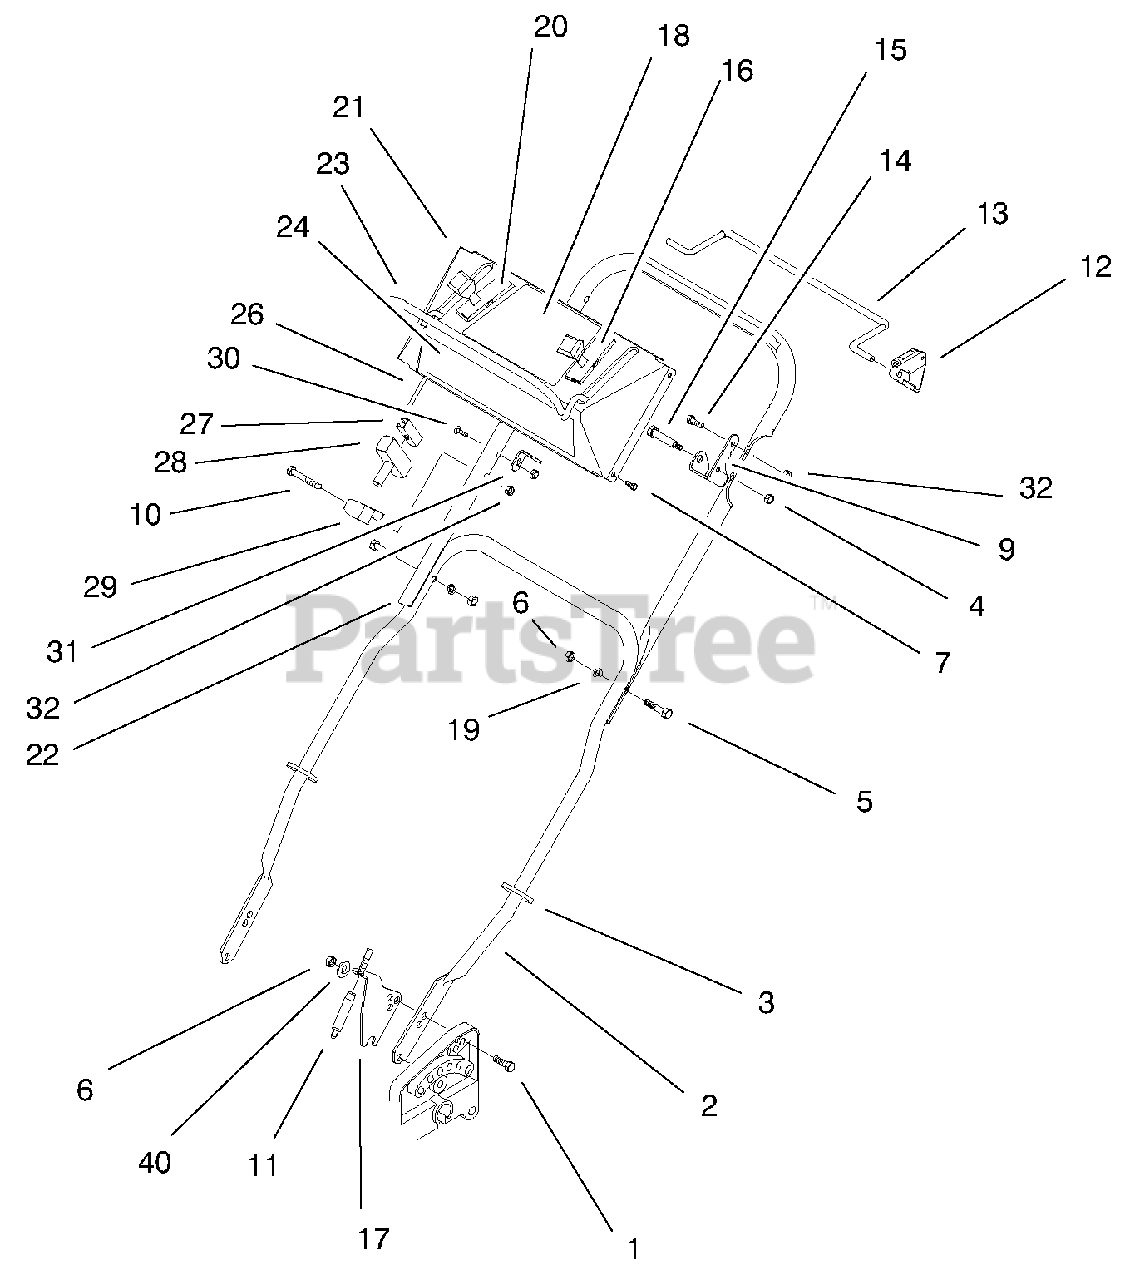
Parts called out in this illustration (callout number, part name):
1	Bolt-CARR
2	Handle Section-Lower
3	Tie Strap
4	Nut-Lock
5	Screw-HH
6	Nut-Lock
7	Screw-Phil
9	Bail Stop Bracket
10	Bolt-Hex
12	Stop-Pivot
13	Bail-Sp Control
14	Screw-HH
16	Throttle Cable
17	Bracket-Traction Cable
18	Decal-Control Panel
20	Control-Speed
21	Panel-Control
22	Handle-Upper
23	Engine Control Bail
24	Decal-Console
26	Cable-Control
27	Clip-Rope
28	Handle-Starter
29	Guide-Rope
30	Handle Screw
31	Bracket-Cable Anchor
32	Nut-Lock
39	Nut-Lock
40	Washer-Flat
